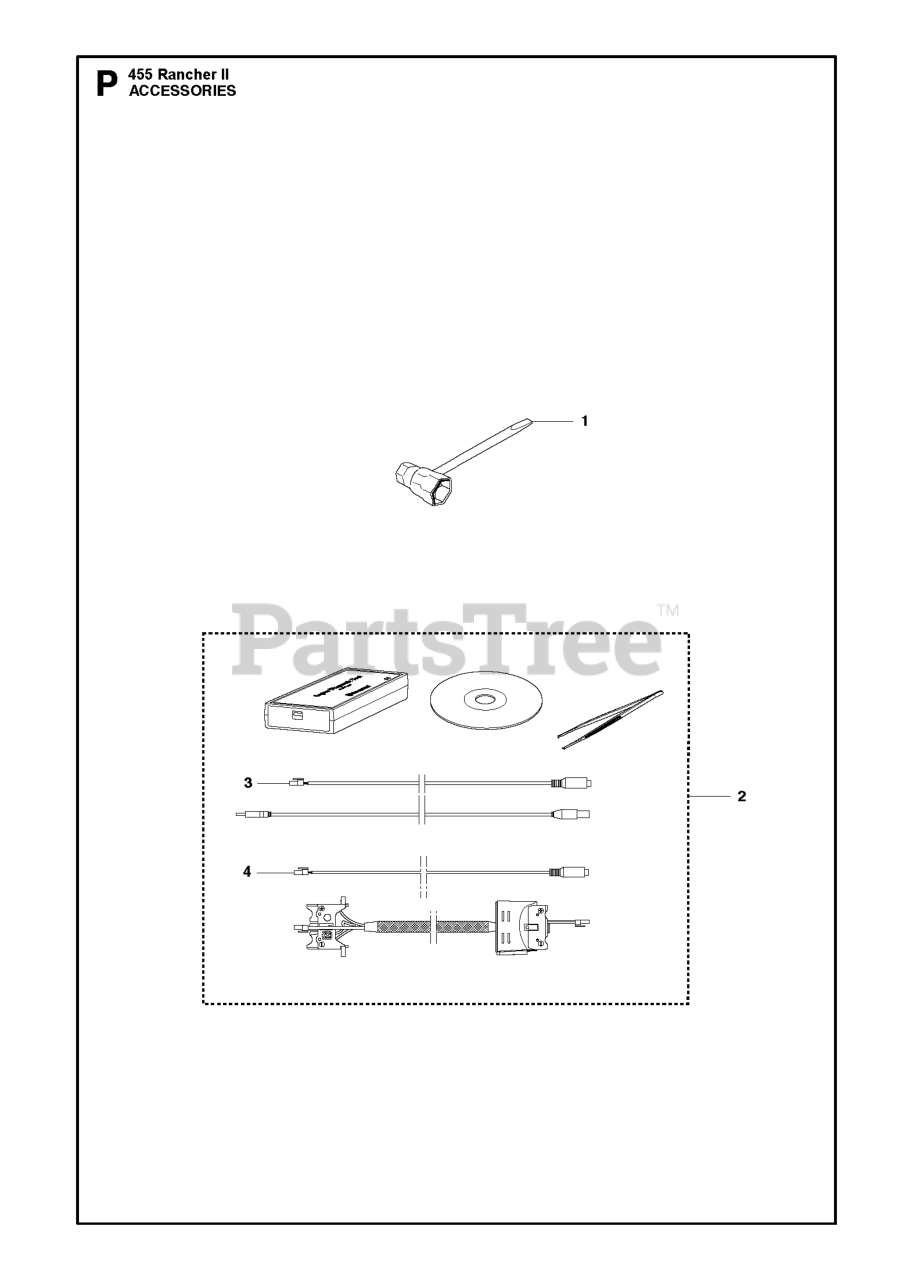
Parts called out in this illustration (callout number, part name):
1	COMBI TOOL
2	DIAGNOSTIC TOOL KIT
3	CABLE ASSY
4	CABLE ASSY
